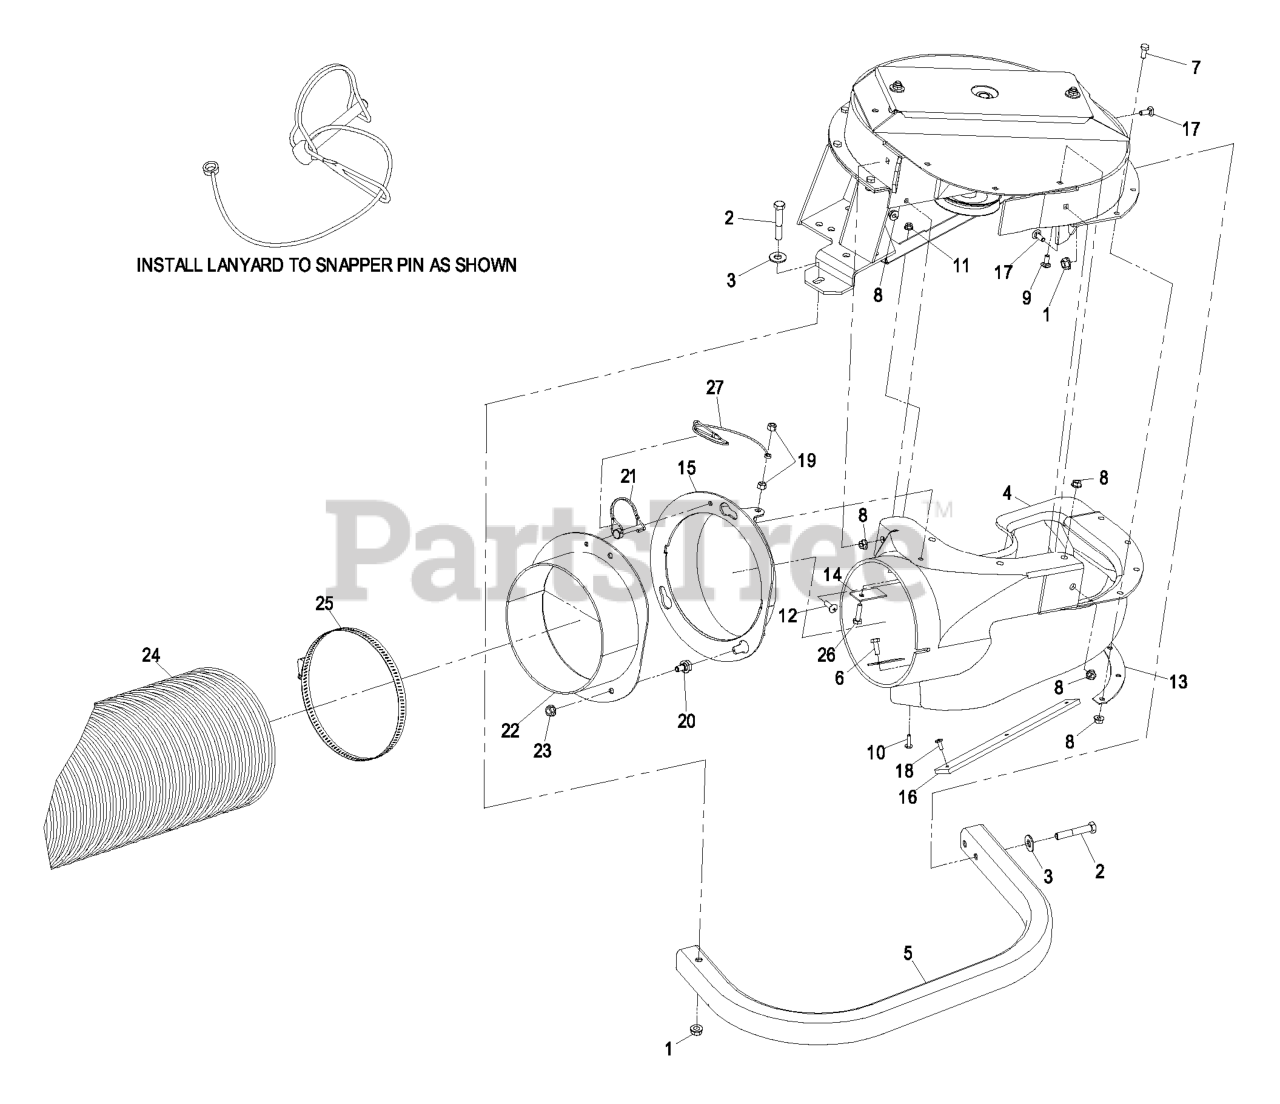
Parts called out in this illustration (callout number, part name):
1	NUT-HHF, WHIZ
2	SCREW-HH
3	WASHER-FLAT
4	ASM,BLOWER CHUTE
6	SCREW-HH
7	SCREW-HH
9	SCREW-CARR
10	SCREW-HEAD, TRUSS
13	PLATE-BACKING, BLOWER
14	PLATE-BACKING
16	PLATE,REINFORCEMENT LARGE
17	BOLT-CARR
18	RIVET-BLIND
19	NUT-LOCK, NI
20	BOLT-SHOULDER,HFH
21	PIN-HITCH
22	WLD,FRUVD HOSE ADAPTER
24	HOSE,FRUVD
26	SCREW-HH
27	LANYARD-NYLON
